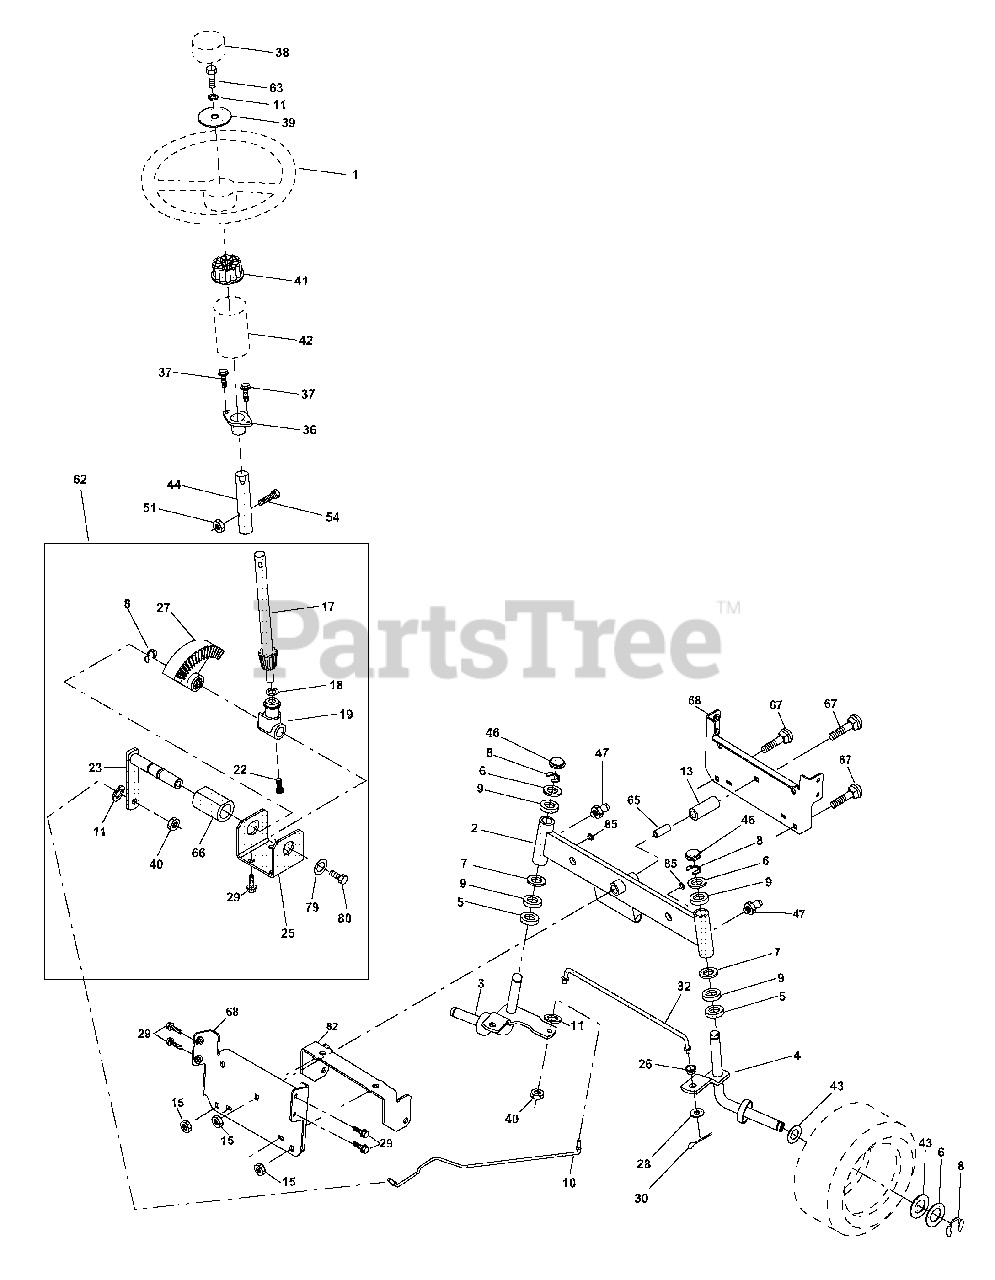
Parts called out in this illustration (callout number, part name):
1	Wheel Steering Auto Black
2	Axle Asm Front
3	Spindle Asm Lh
4	Spindle Asm Rh
5	Bearing Race Thrust Harden
6	Washer 25/32 X 1 5/8 X 16 ga
7	Washer 27/32 X 1 1/4 X 16 Ga
8	Ring Klip #t5304-75
9	Bearing Col Strg Blk
10	Link Drag Extended
11	Lockwasher
13	Spacer Bearing Axle Front
15	Hex Flange Lock
17	Shaft Asm Strg 5/8 X 15 19 Lt
18	Washer Thrust 515 x 750 x 033
19	Support Shaft
22	Screw Hex Wsh Hd Torx
23	Shaft Asm Pittman
25	Bracket Steering
26	Bushing Rod Tie Blk Lt
27	Gear Sector
28	Washer 13/32 X 7/8 X 16ga
29	Screw 3/8-16x3/4
30	Pin
32	Rod Tie Wire Form 19 75 Mech
36	Bushing Strg 5/8 Id Dash
37	Screw TT #10-32 x 5 x 3/8 Flange
38	Insert Cap Strg
39	Washer 13/32 x 2-3/8 x 12Ga
40	Locknut Center
41	Adaptor Wheel Strg 640/ 635id
42	Boot Dash Steering
43	Washer 25/32 X 1 1/4 X 16 Ga
44	Extension Steering Non-Adjust
46	Cap Spindle Fr Top Blk
47	Fitting Grease
51	Nut Lock Hex W/Ins.
54	Bolt Fin Hex 5/16-18 Unc P
62	Kit Steering Assembly Service
63	Bolt Fin Hex 3/8-16unc x Gr. 5
65	Spacer Brace Axle
66	Bearing Arm Pittman
67	Bolt Rdhd Sq 3/8-16 Unc x 2-3/4
68	Brace Axle
79	Washer 13/32 x 1-1/4 x 12 Ga
80	Bolt Hex Nylon 3/8-16 x 3/4
82	Bracket Susp Chassis Front
85	Fastener Christmas Tree
